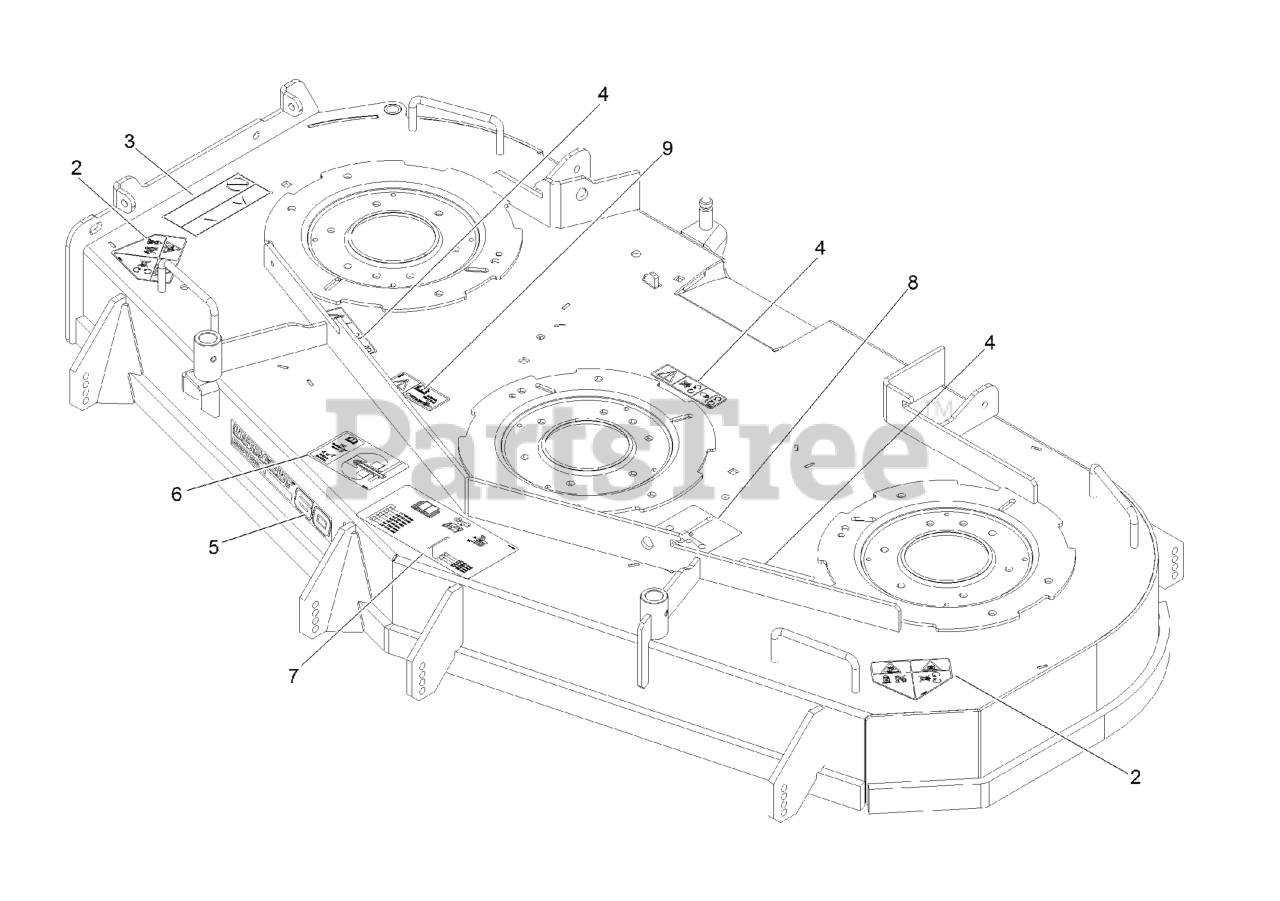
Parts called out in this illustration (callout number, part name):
2	DECAL-DANGER
3	DECAL-WARNING THROWN OBJ
4	DECAL-COVER, MISSING
5	DECAL, 604
6	DECAL-ROLLER MOUNTING
7	DECAL-ANTI-SCALP
8	DECAL-BELT ROUTING
9	DECAL-BOLT TORQUE
